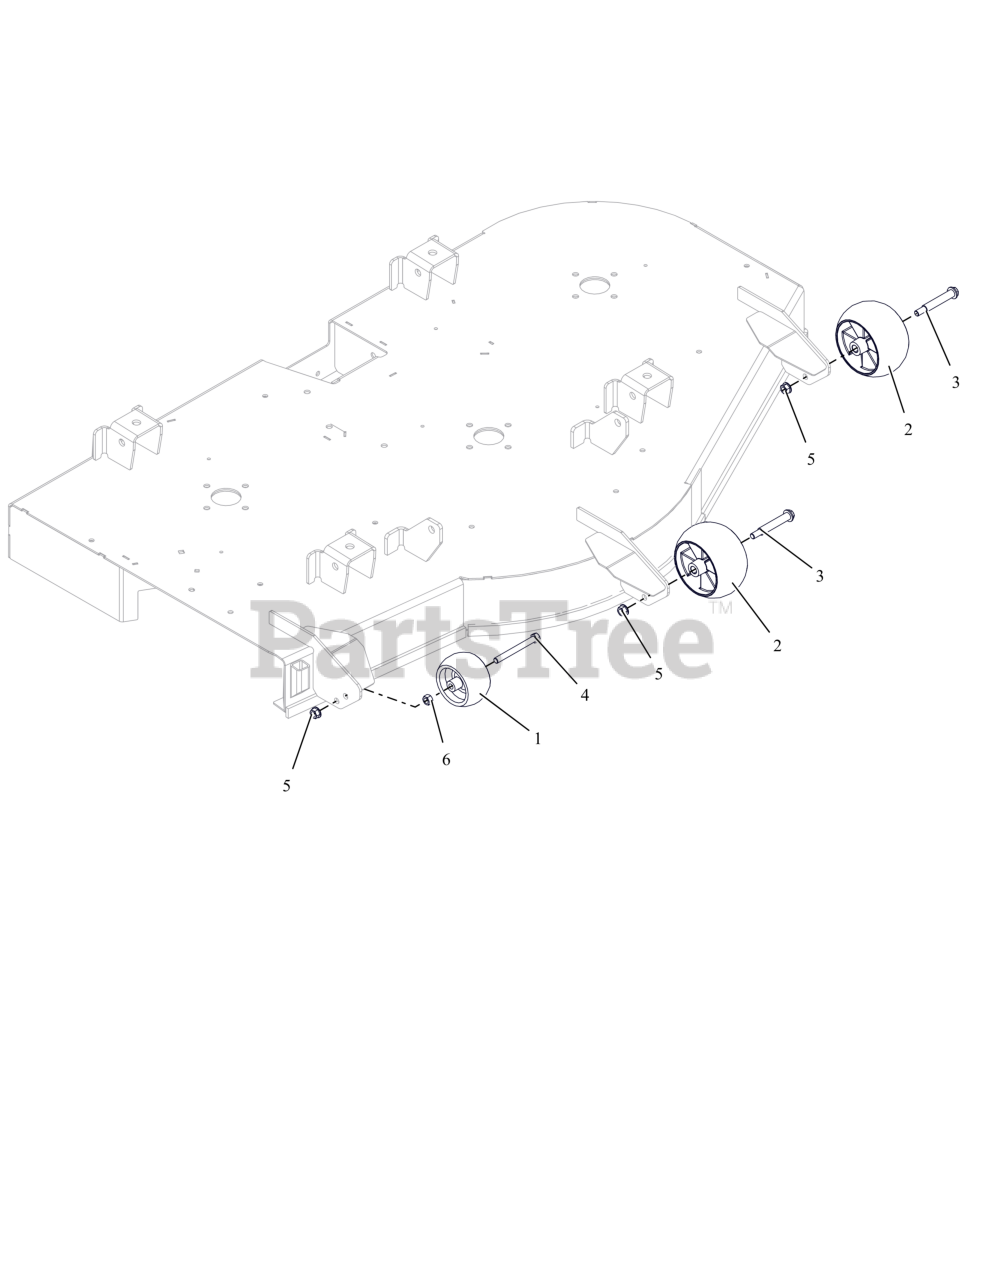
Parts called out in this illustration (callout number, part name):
2	ANTI-SCALP WHEEL - 5X OS
3	BLT-SHLDR .38-16X2.50 HWH G5
4	BLT, HEX .38-16X3.50 G5 ZCC
5	NUT-LK-CTR-FLG .375-16 GF ZCC
6	NUT-STD .375-16 G2 ZCC
